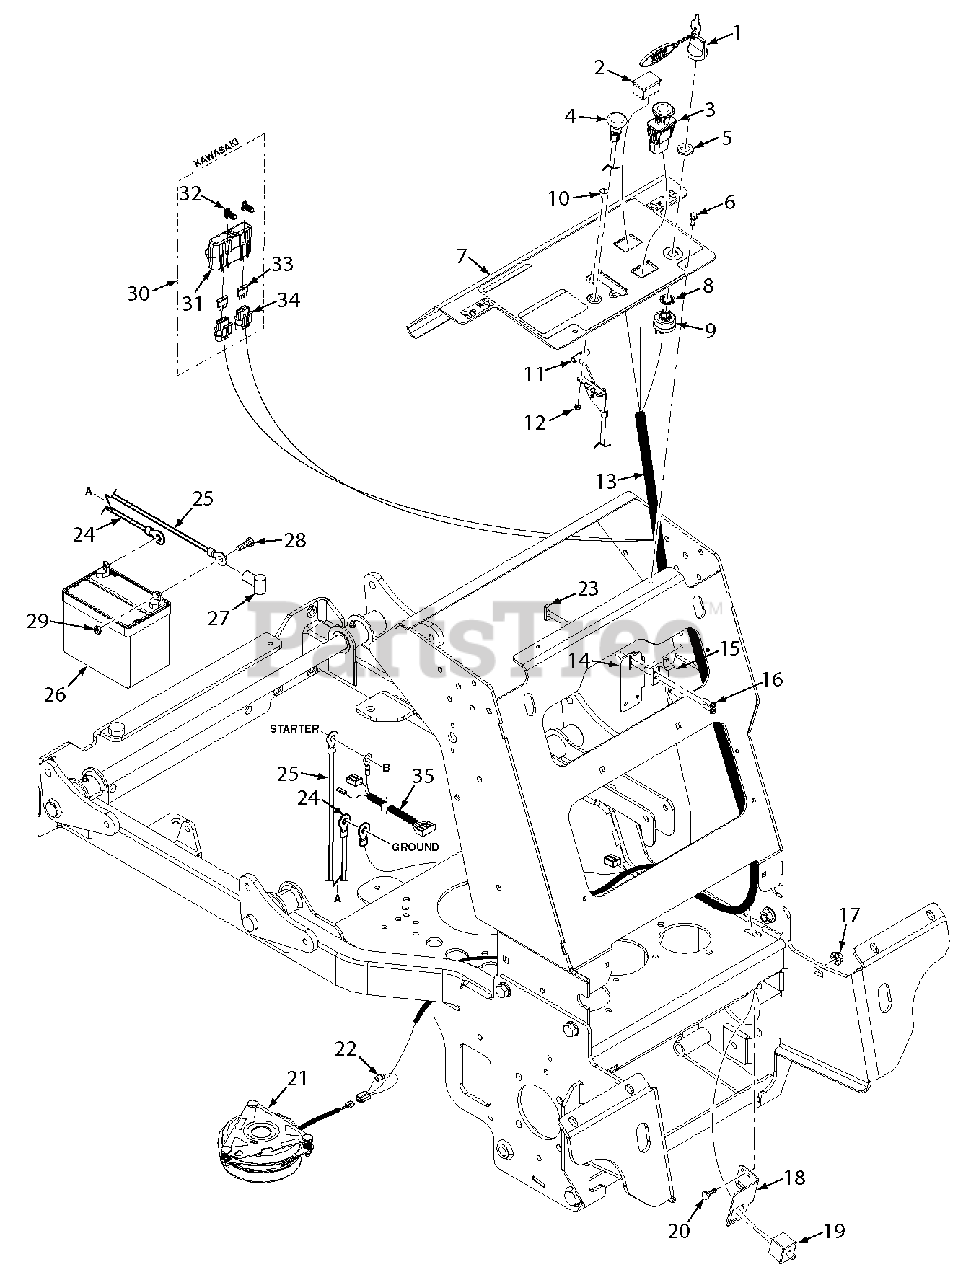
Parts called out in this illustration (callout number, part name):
1	Key Assy. w/Fob
2	Hourmeter, Inductive
3	Switch, PTO
4	Choke Control
5	Nut, Special 5/8-32
6	Screw, 1/4-20 x 3/4" Taptite
7	Instrument Panel w/Decal - SVRII
8	Lockwasher, 5/8" Internal Tooth
9	Switch, Key
10	Bolt, Carriage #10-24 x 1/2"
11	Throttle Control
12	Nut, Elastic Stop #10-24
13	Wire Harness, SVRII-36
14	Bracket, Neutral Switch
15	Switch, Interlock - DPDT
16	Screw, #10-24 x 3/4" Taptite
17	Nut, Serrated Flange 1/4-20
18	Switch Bracket, Operator Presence
19	Switch, Double Pole - N.O. / N.O.
20	Nut, Serrated Flange 1/4-20
21	Clutch w/Tag GT2.5-FE02
22	Diode, 600V - 6A
23	Plate, Threaded
24	Cable, Battery - Black 39"
25	Cable, Battery - Red 44" w/Braid
26	Battery, 350 CCA (not available through Scag)
27	Rubber Boot
28	Bolt, Hex Head 1/4-20 x 3/4"
29	Nut, 1/4-20
30	Double Fuse Assy.
31	Cover, Sealed Double
32	Clip, Wire
33	Fuse, 20 Amp
34	Fuse Holder
35	Wire Harness Adaper - Kawasaki
